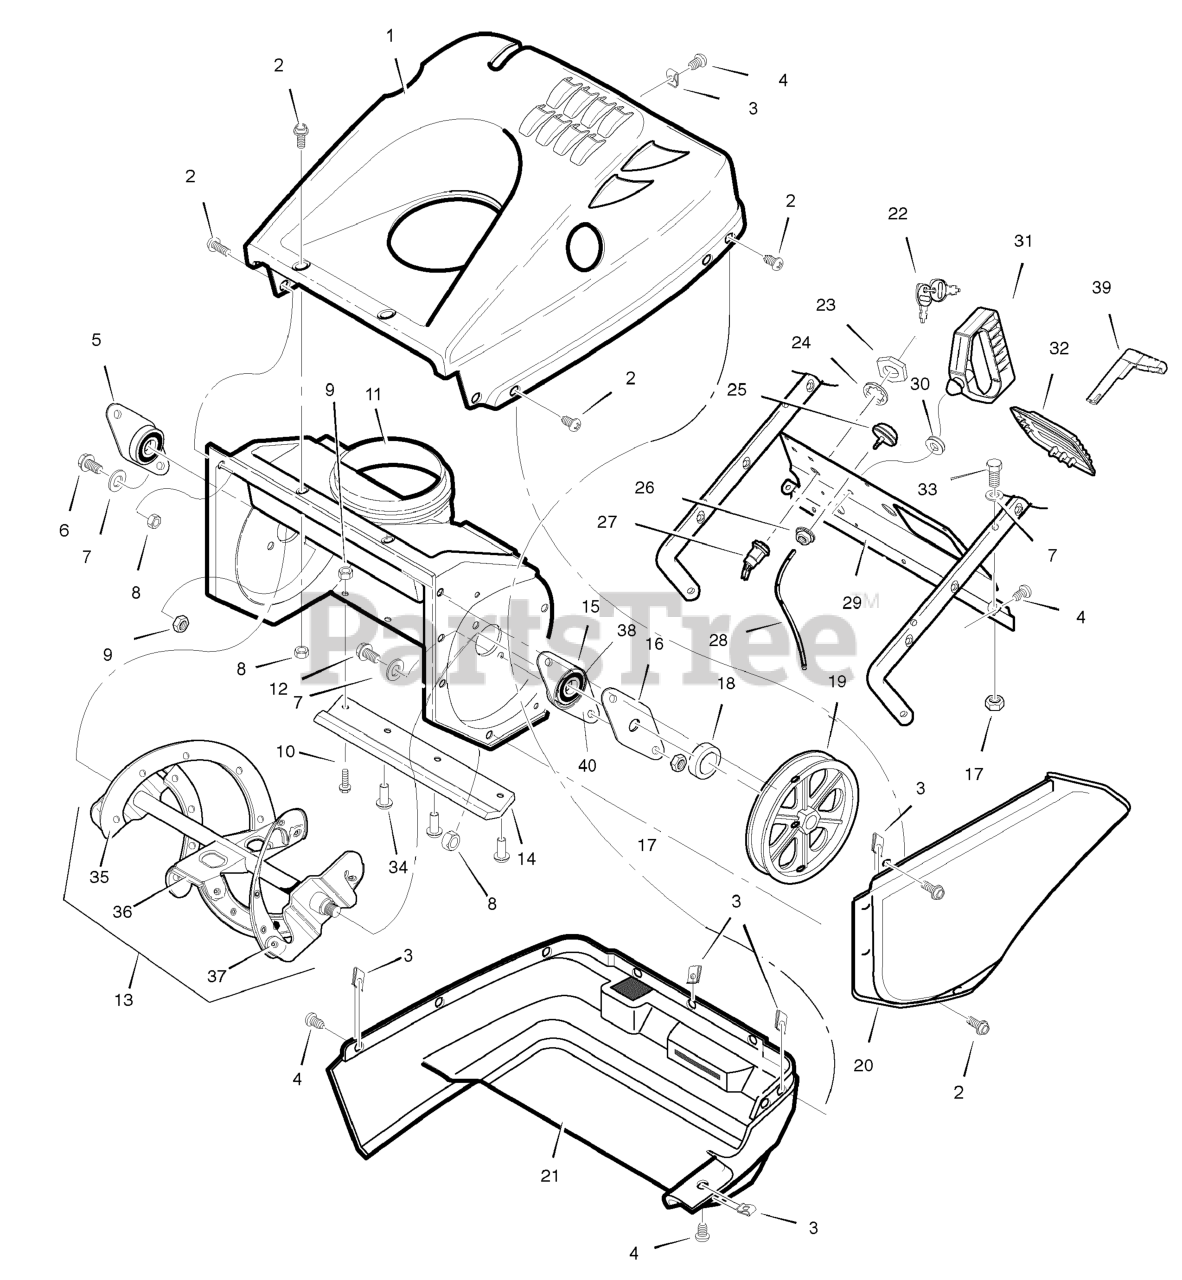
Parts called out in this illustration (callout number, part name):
1	COVER, TOP
2	SCREW, #10-24 X 0.50
3	NUT, 1/4-10 SPEED J-TYPE
4	SCREW, 1/4-14 X 0.75
5	FLANGE BEARING
6	SCREW, 1/4-20 X 1.00
7	WASHER, FLAT
8	NUT, #10-24 HEX CONTROL LOCK
9	NUT, 1/4-20 HEX CONTROL LOCK
10	SCREW, 1/4-20 X 0.75
11	AUGER HOUSING ASSEMBLY
12	SCREW, 1/4-20 X 0.63
13	AUGER ASSEMBLY, COMPLETE
14	BLADE, SCRAPER
15	SF BEARING & PLATE ASSEMBLY
16	LT PLATE, RETAINER BEARING
17	NUT, 1/4-20 HEX CONTROL LOCK
18	SPACER, SLEEVE
20	COVER, BELT
21	COVER, BOTTOM
22	SET, Key
23	NUT, 5/8-32
25	PRIMER-CARBURETOR
26	NUT, 1/-20 HEX KEPS
27	SWITCH, IGNITION 45 DEG.
28	HOSE, PRIMER 9.5"
29	PANEL, CONTROL
30	GROMMET & WASHER, ROPE
31	GRIP, Starter Rope
32	PANEL, ACCESS SPARK PLUG
33	SCREW, 1/4-20 X 1.25
34	RIVET, OFFSET
35	BLADE, AUGER
36	BLADE, CENTER
37	RIVET, OFFSET
38	BEARING, BALL
39	KNOB-CHOKE SHAFT
40	RETAINER, BEARING
